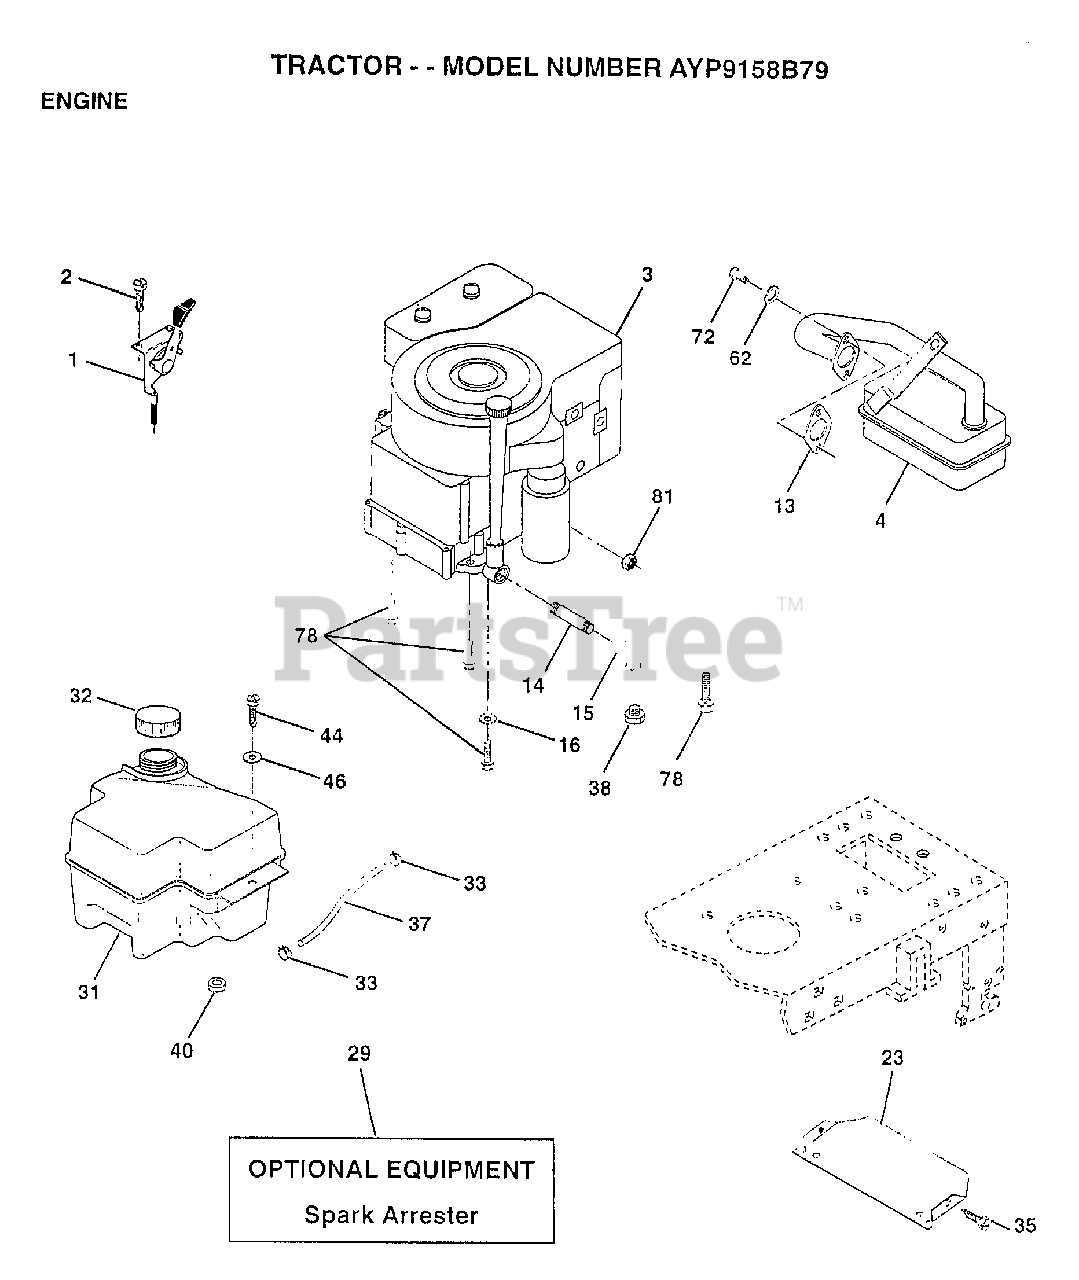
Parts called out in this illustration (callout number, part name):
1	CONTROL THROTTLE
2	SCREW LT
4	MUFFLER
13	GASKET ENG 1 313 LD TIN PLATED
14	PIPE NIPPLE
15	ELBOW
16	LOCKWASHER
23	SHIELD-HEAT
32	CAP ASM FUEL
33	HOSE CLAMP
35	SCREW
37	LINE FUEL
44	SCREW HEX CRT
46	WASHER
49	SCREW GTV
62	LOCKWASHER
72	SCREW
78	SCREW
81	NUT
